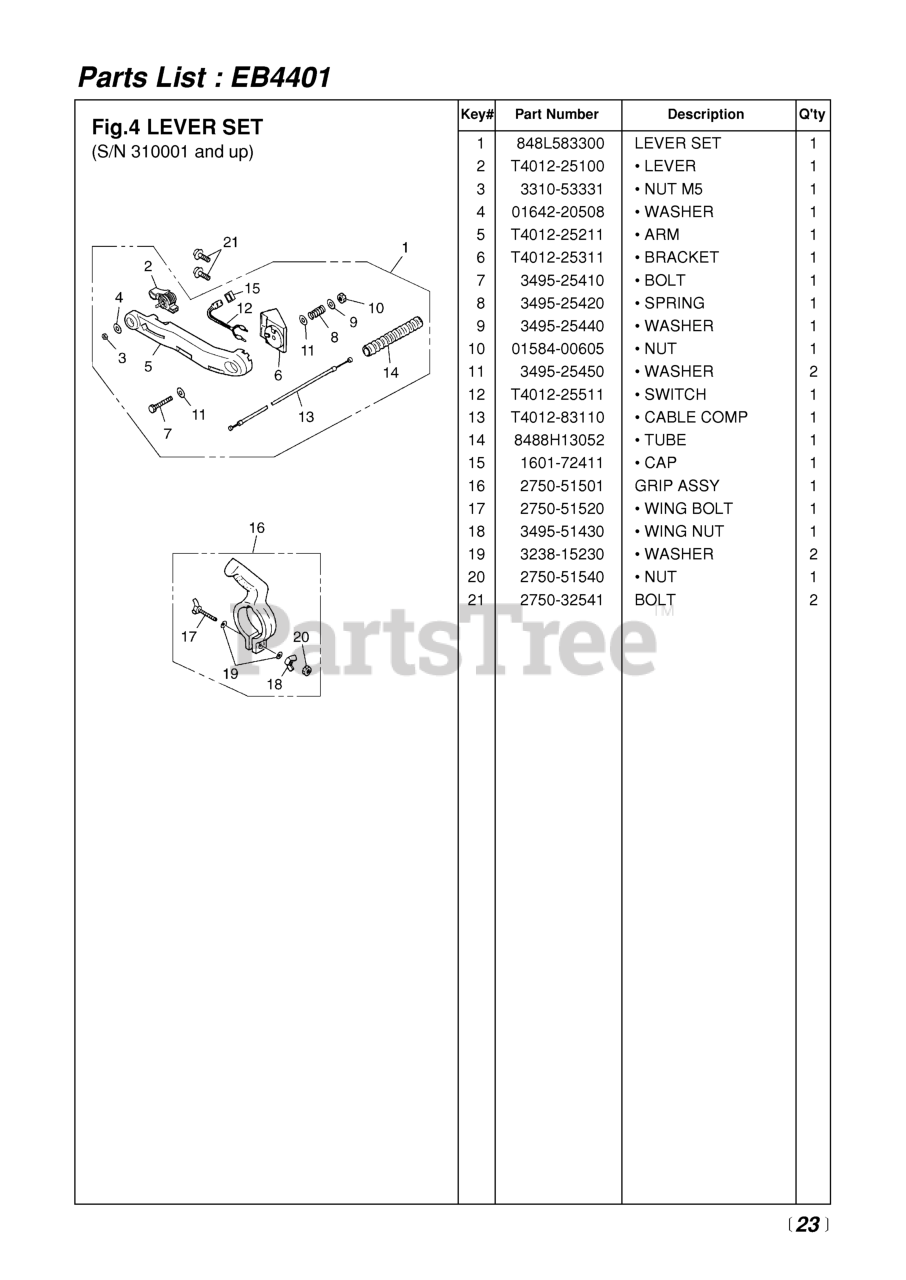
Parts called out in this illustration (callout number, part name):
1	LEVER SET (RPLS. T4012-25001)
2	LEVER
3	NUT (B)
4	WASHER, M5x.8(RPLS 01624-20508
5	ARM (RPLS T4012-25210)
6	BRACKET (RPLS -25310)
7	BOLT
8	SPRING
9	WASHER
10	NUT, M6 X 5
11	WASHER, FLAT
12	SWITCH (RPLS T4012-25510)
13	CABLE COMPLETE
14	TUBE (REPLACES T4012-25610)
15	CAP SWITCH
16	GRIP ASSEMBLY (RPLS -51500)
17	WING BOLT
18	NUT, WING
19	WASHER
20	NUT
21	BOLT, M5 X 16 (RPLS -32540)
